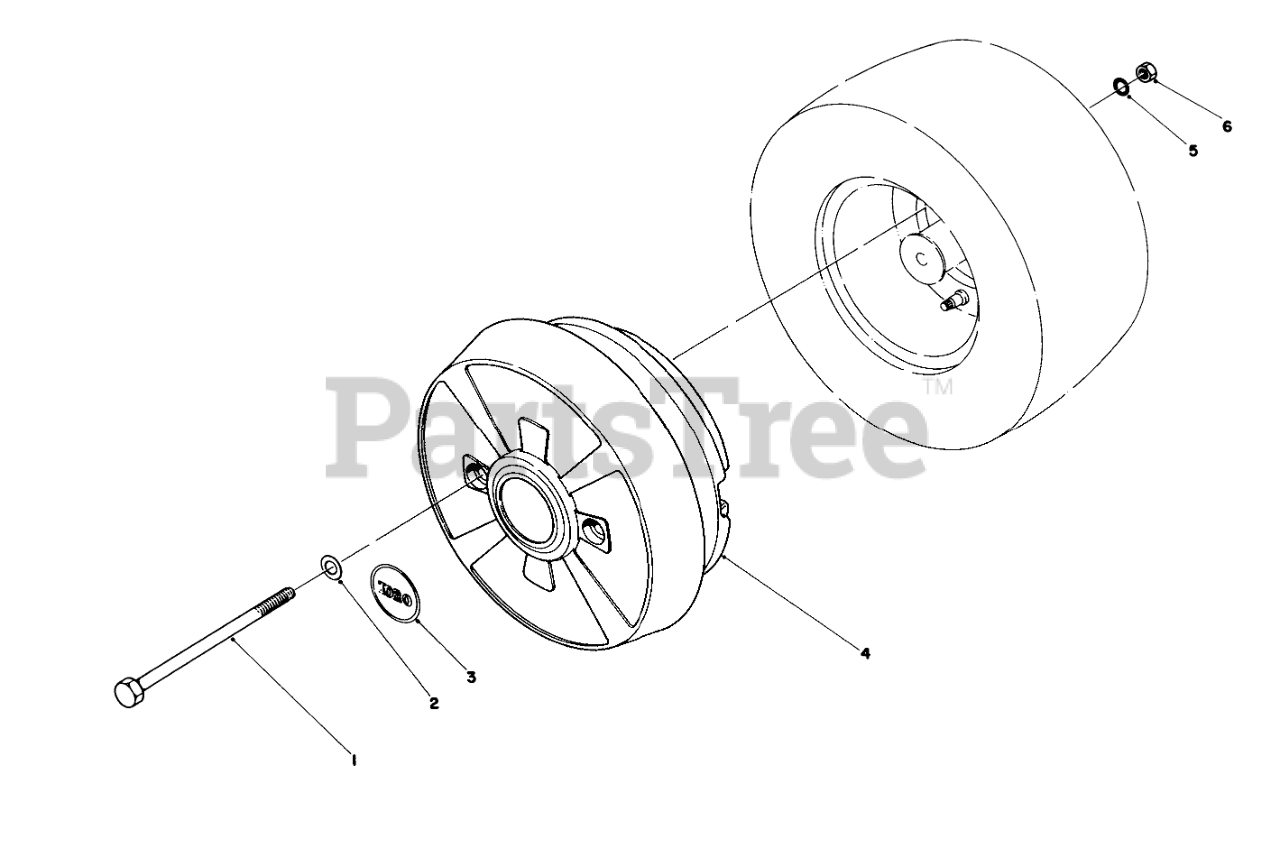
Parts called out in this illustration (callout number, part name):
1	SCREW-HH
2	WASHER-FLAT
3	Decal
4	WHEEL WEIGHT
5	WASHER-LOCK
6	NUT-HEX
